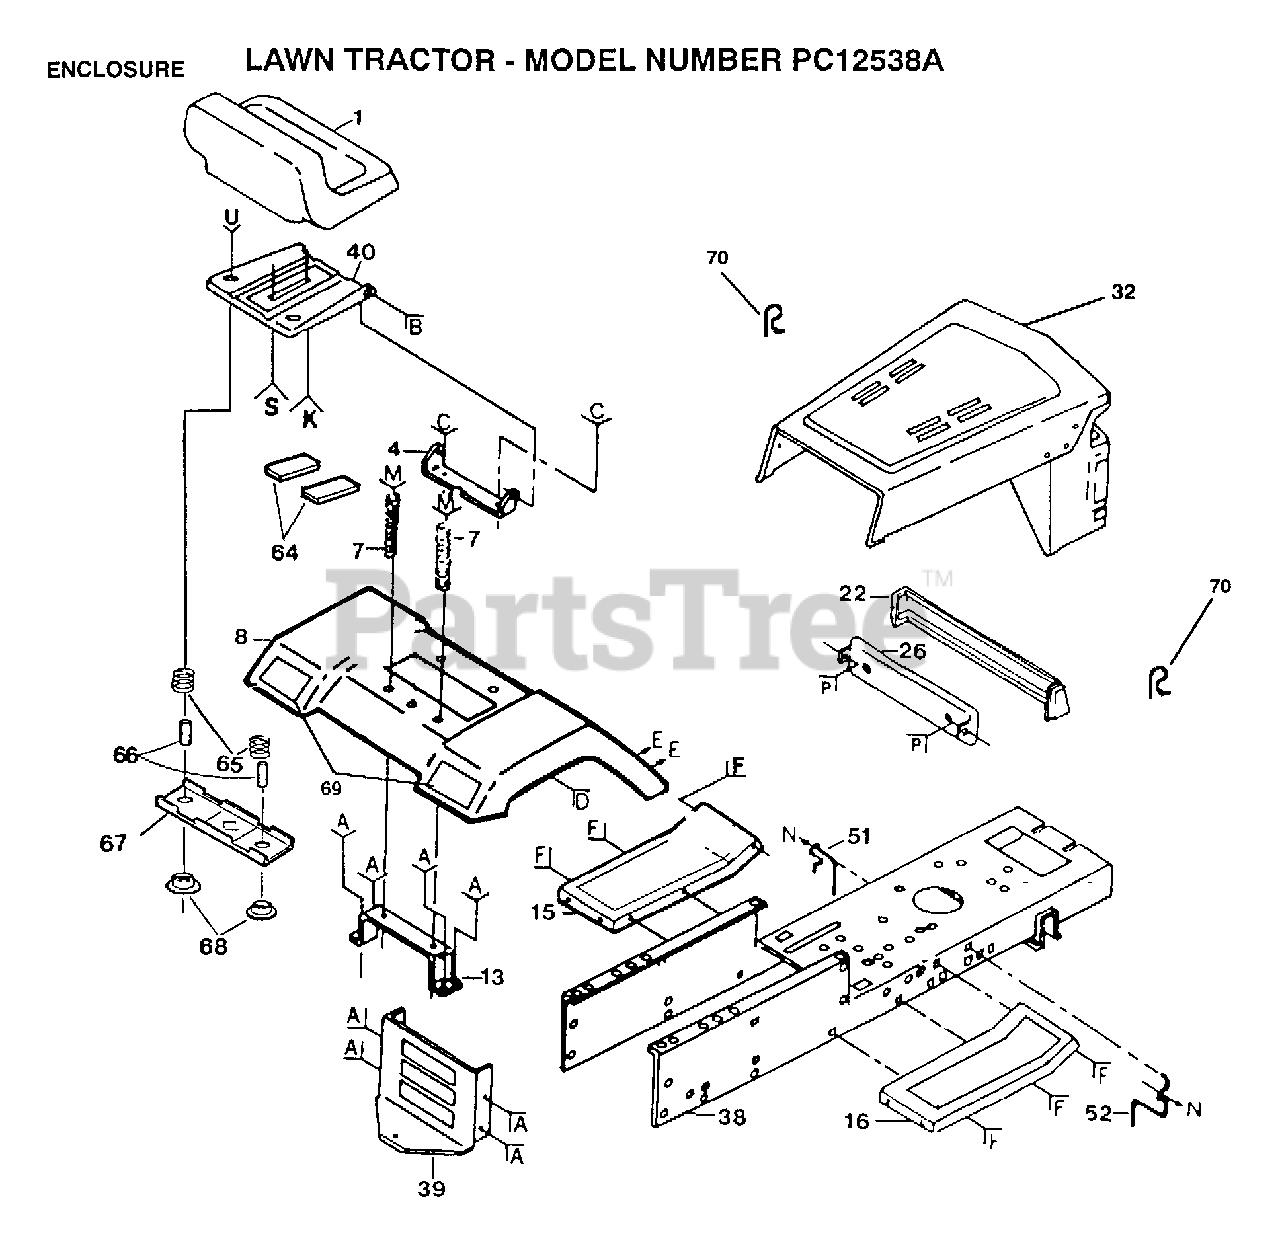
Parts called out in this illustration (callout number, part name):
7	SPRING COMPRESSIO
15	FOOTREST LH
16	FOOTREST RH
32	HOOD&GRILL ASSY
38	CHASSIS ASS'Y
51	BELT GUIDE
52	BELT GUIDE
64	STRIP FORM
66	SPACER SPLIT
67	BRKT SWITCH
68	BUSHING
69	REFLECTOR-TAIL YT
70	SPRING.RETAINER
